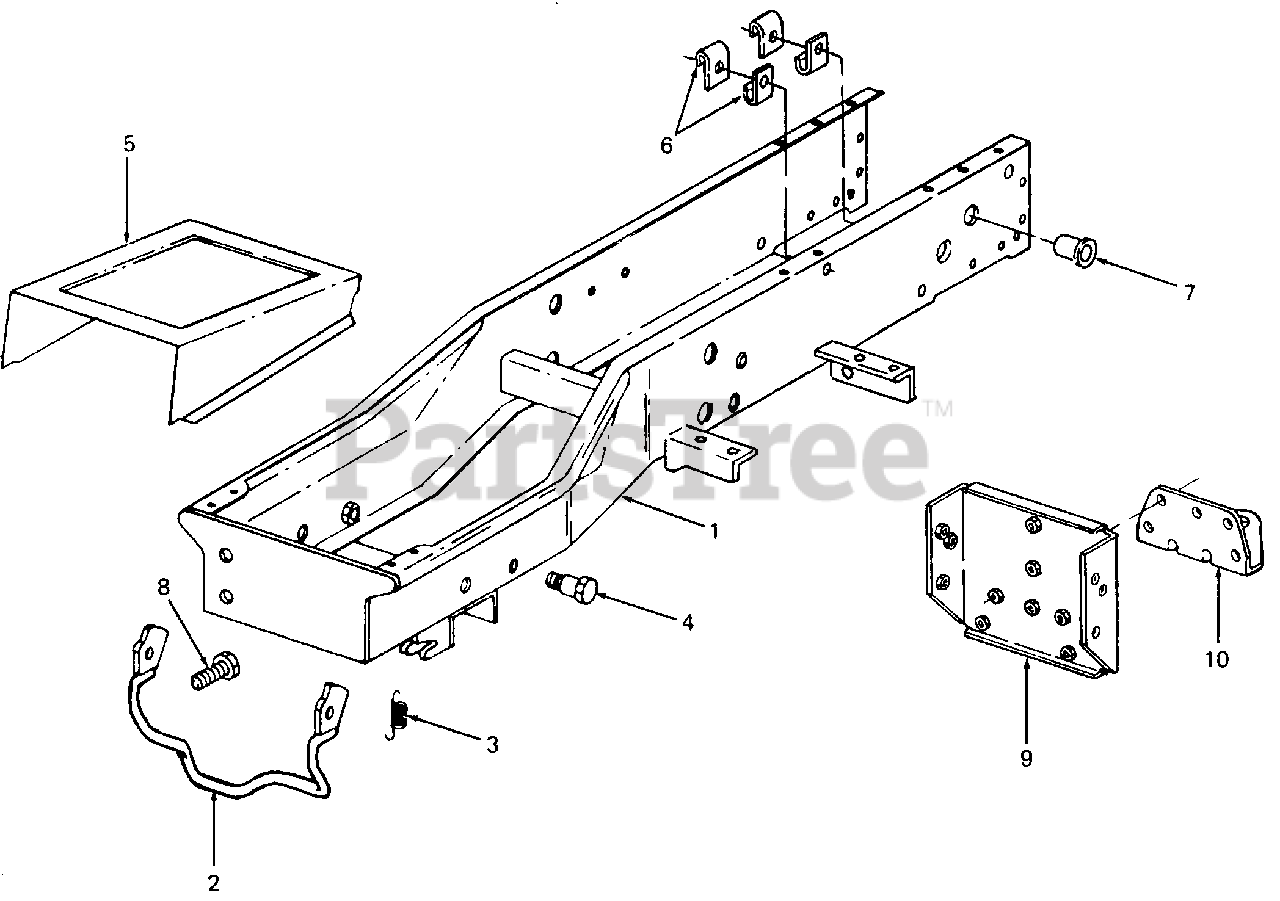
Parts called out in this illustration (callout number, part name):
1	Frame Assy
3	Spring, Latch
4	Bolt, Shoulder
5	Cover, Frame w/Graphic
6	Clip, Cable
7	Bushing, Snap
8	Screw, Adjustment, 1/2-20 X 1.0 Lg GR5
9	Plate Assy, Hitch
